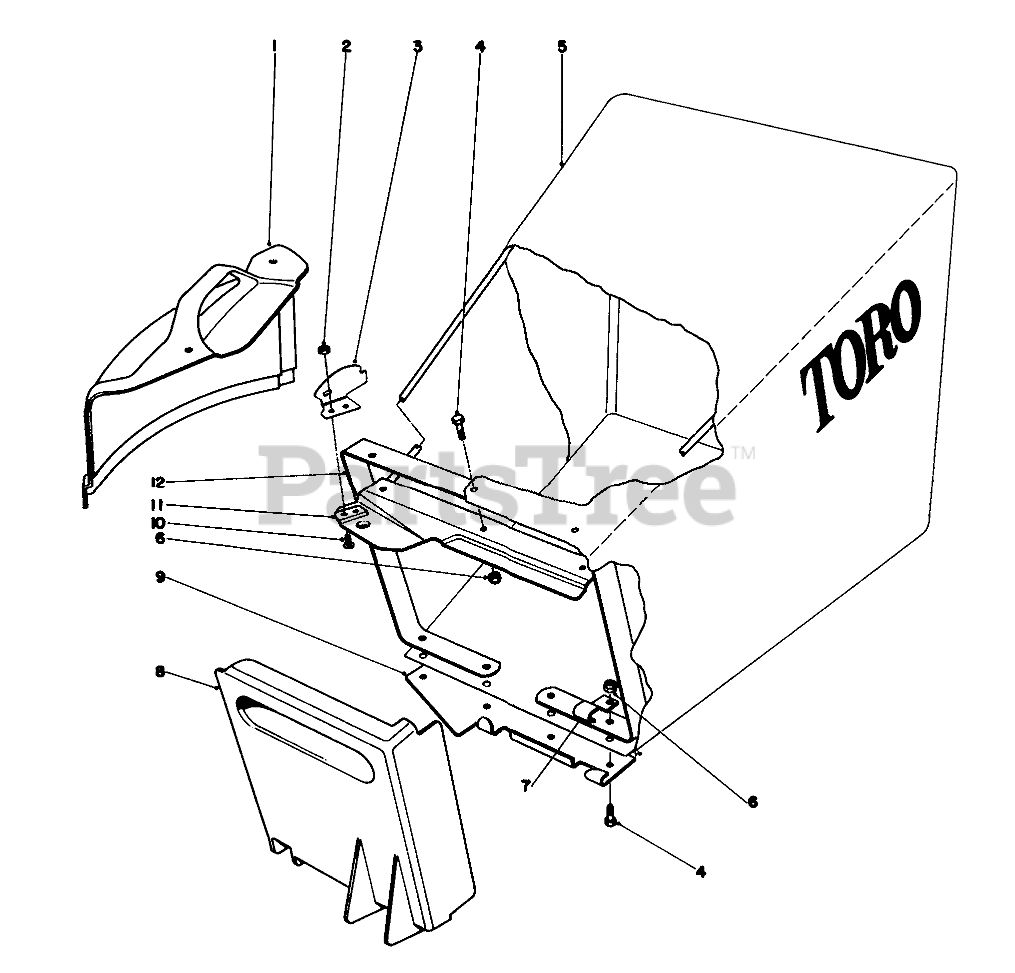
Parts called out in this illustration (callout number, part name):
1	Cover
2	NUT-LOCK
3	Latch Bag
4	SCREW-HWH
5	REPLACMNT BAG 44-0530
6	NUT-LOCK, SIDE
7	SUPPORT BRACKET
8	BAG DOOR
9	DOOR BRACKET
10	Screw
11	Bag Frame
12	LOWER BAG FRAME
